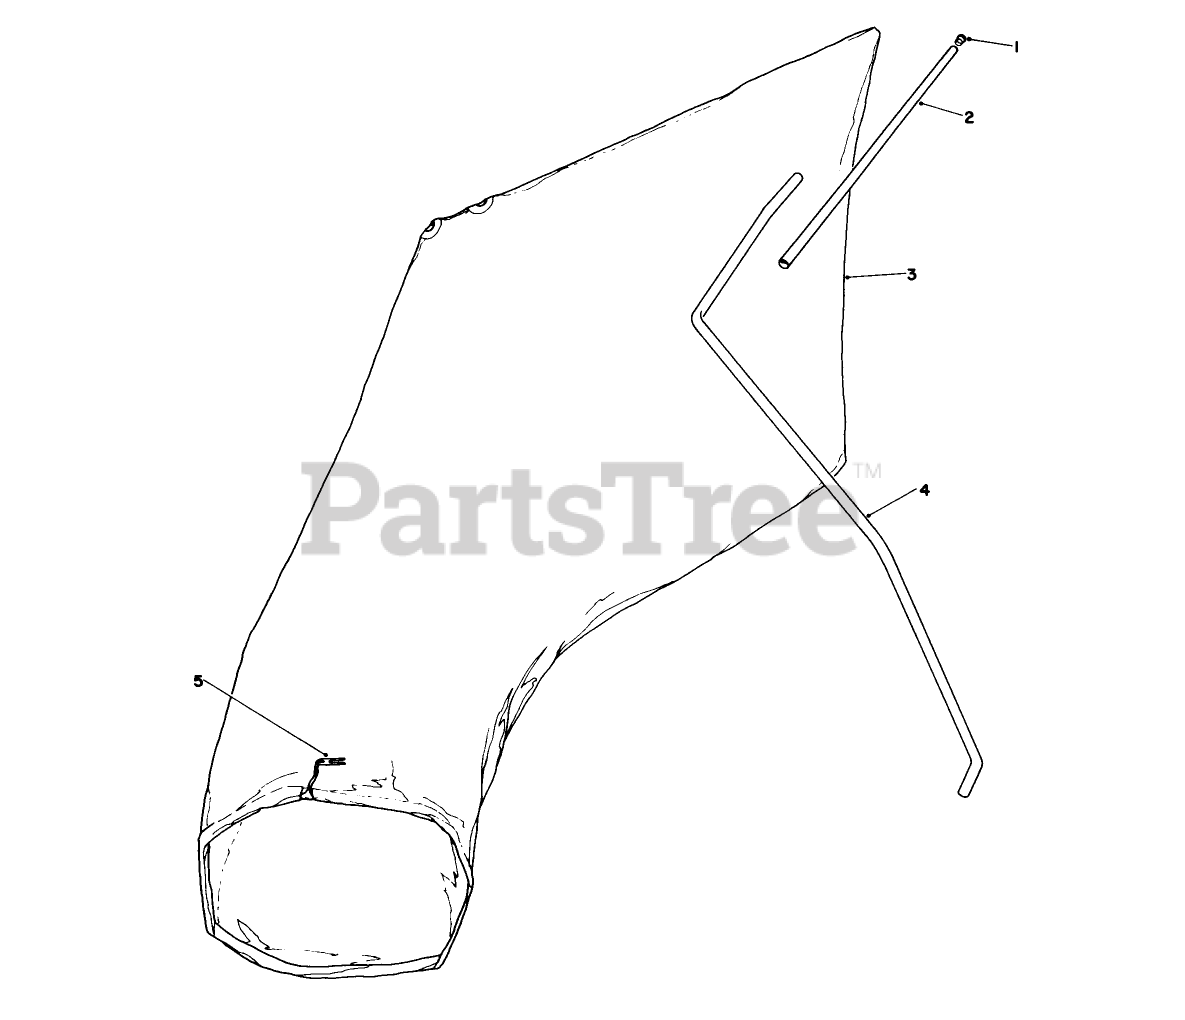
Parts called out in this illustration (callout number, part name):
2	BAG HANGER TUBE
3	Bag (Incl. Ref. #5)
4	HANGER ROD
5	BAG CORD FASTENER
